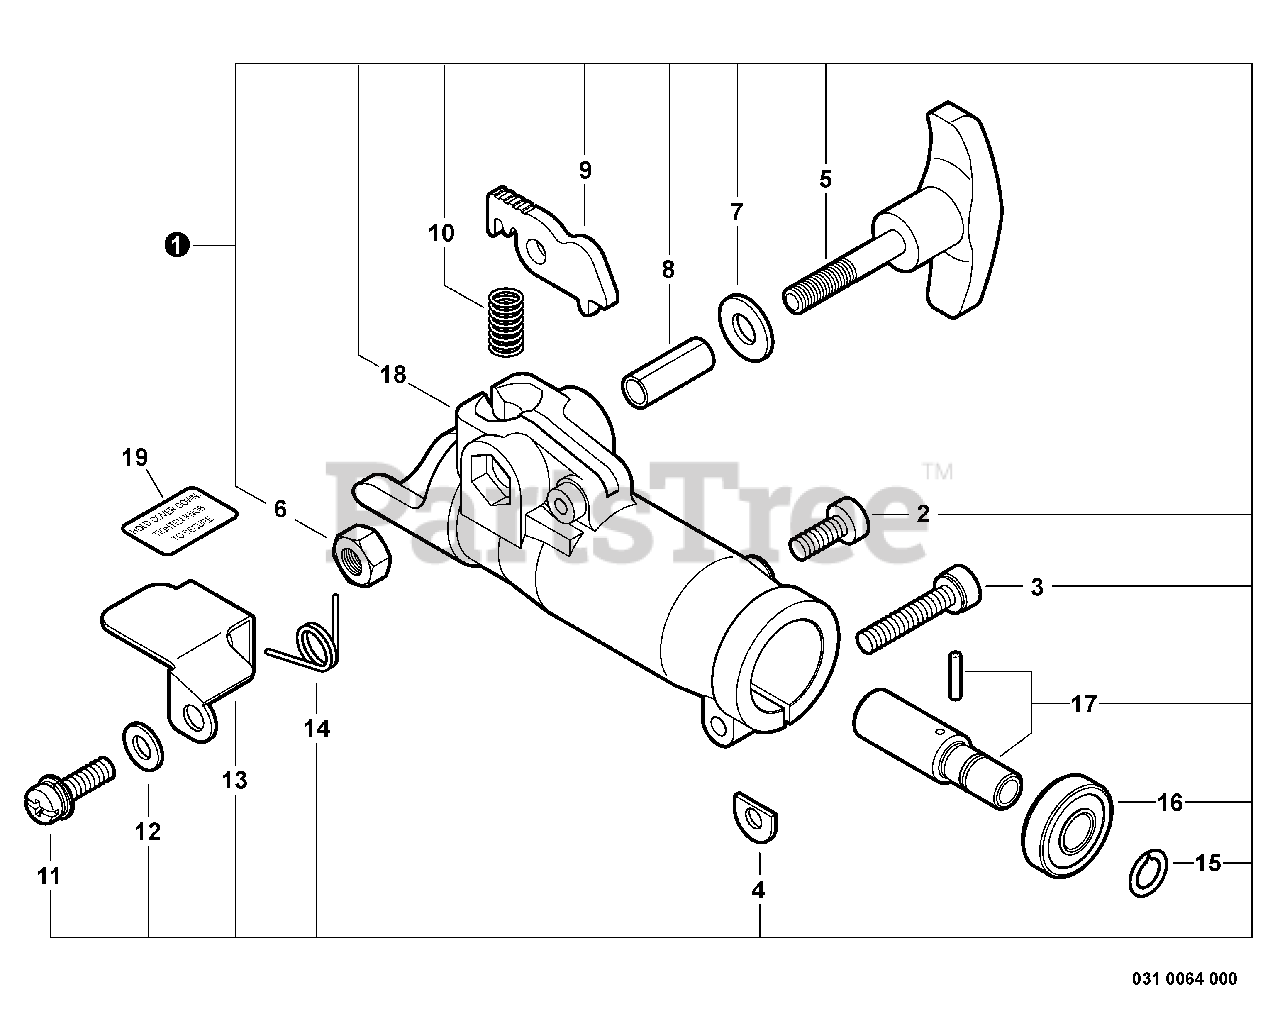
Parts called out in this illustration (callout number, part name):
1	COUPLER ASSY
2	SCREW - 5X12
3	SCREW - 5X25
5	THUMBSCREW
6	NUT - 6
7	WASHER - 6
11	SCREW - 5X12
12	WASHER - 5 -- SPRING
13	COVER, LATCH
15	RING, RETAINING - 9
16	BEARING, BALL - 609ZZ
17	SHAFT KIT
18	CASE, COUPLER
19	LABEL - INSTRUCTION
